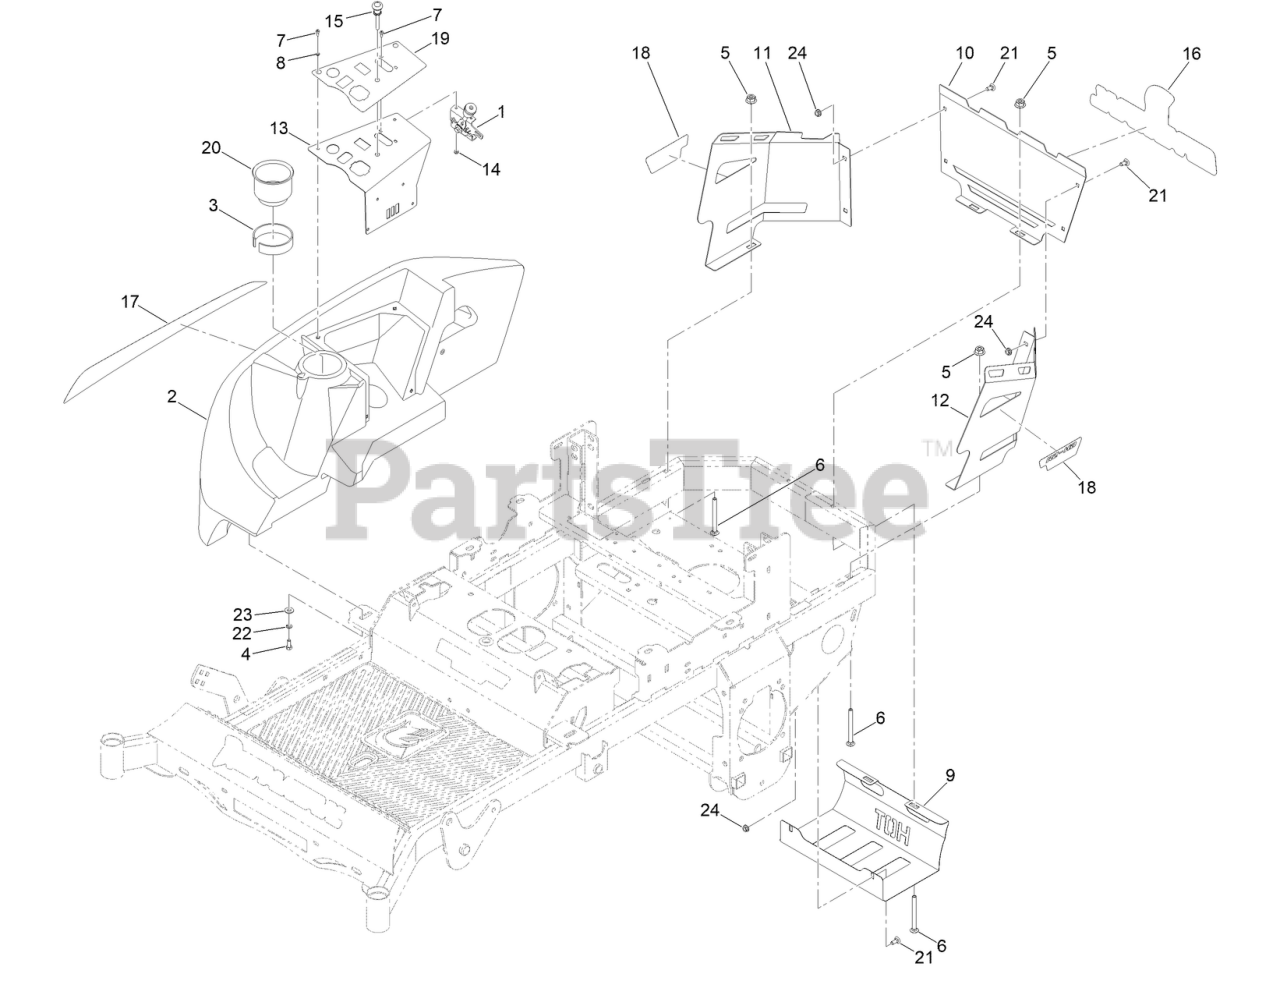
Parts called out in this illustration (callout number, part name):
1	NUT-LOCK
2	CONSOLE W/ CUPHOLDER
3	TAPE-FOAM
4	SCREW-HH
5	3/8-16 NYLON INSERT FLANGE L/NUT YZ
6	3/8-16 X 4 CARRIAGE BOLT ZINC
7	10-24 X 1/2 SOCKET C/S 18-8 SS
8	#10 SPLIT LOCKWASHER 18-8 SS
9	RZ MWR MUFFLER GUARD PAINTED
10	2021 RZ ENGN COWLING CNTR PAINTED
11	ENGN COWLING RT SIDE RT TANK UPGR PAINT
12	ENGN COWLING LT SIDE RT TANK UPGR PAINT
13	CONTROL PANEL BRKT INDIV CONTROLS PAINT
14	MWR THROTTLE CABLE ASSY W / HANDLE
15	MWR CHOKE CABLE ASSM
16	MWR RR SPARTAN LOGO
17	MWR FUEL TANK LOGO RT SIDE
18	RZ-HD MODEL DECAL
19	RZ-HD/RT/SRT/KGZ-XDE KEYSWTCH CONSL DECL
20	CUP HOLDER
21	BOLT-CARR
22	WASHER-LOCK
23	WASHER-FLAT
24	NUT-HF
